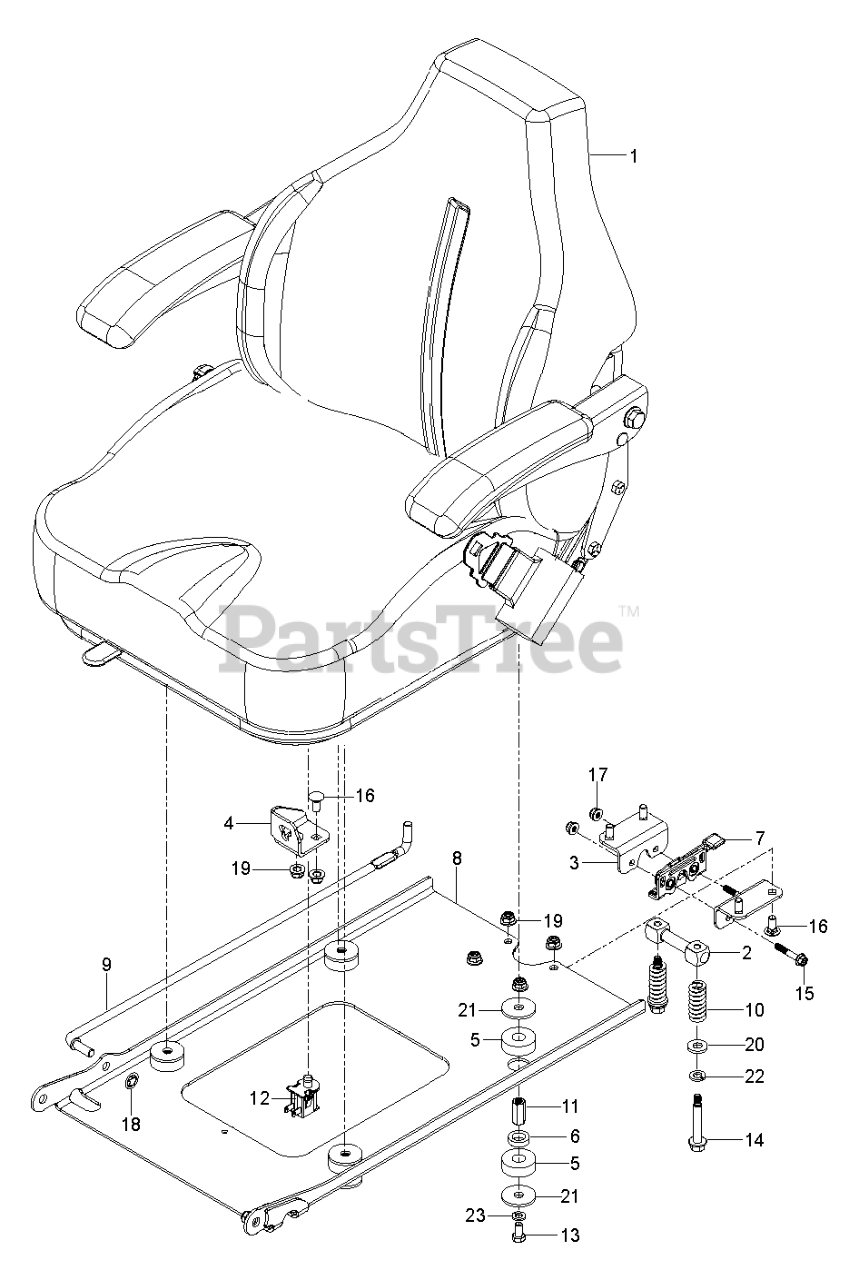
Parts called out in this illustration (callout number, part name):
1	KITS.SEAT.ASSY.TRI-COLOR
2	BAR.LATCH.SEAT
3	BRACKET.MTG.LATCH
4	BRACKET.SEAT.STAY.ROD
6	ISO-MOUNT INSERT
7	LATCH.ROTARY
8	PLATE.PNT.MTG.SEAT.EDIP
9	ROD.SEAT.STAY
11	NUT.HEX.COUPLING.5/16-18X1-1/8
12	SWITCH.SEAT.DP W/RAMPS
13	HCS 5/16-18 X 5/8 GR 5 ZD
14	SCREW.SHLDER.3/8" DIA X 2.5/16
15	SCREW.HHFS.1/4-20X1.5".GR8.ZY
16	BOLT 5/16C X 3/4" CARRIAGE
17	NUT.FLG.NYLOCK.1/4-20.GR.G.ZY
18	NUT 3/8 PALNUT RTNG BLK PHOS
19	5/16-18 NYLOC FLANGE NUT
20	WASHER, 3/8 THICK
21	WASHER.13/32 X 1 X 1/2.11GUARD
22	SLW 3/8 STD
23	WASHER.LOCK.HVY.HLCL.SPR.5/16
